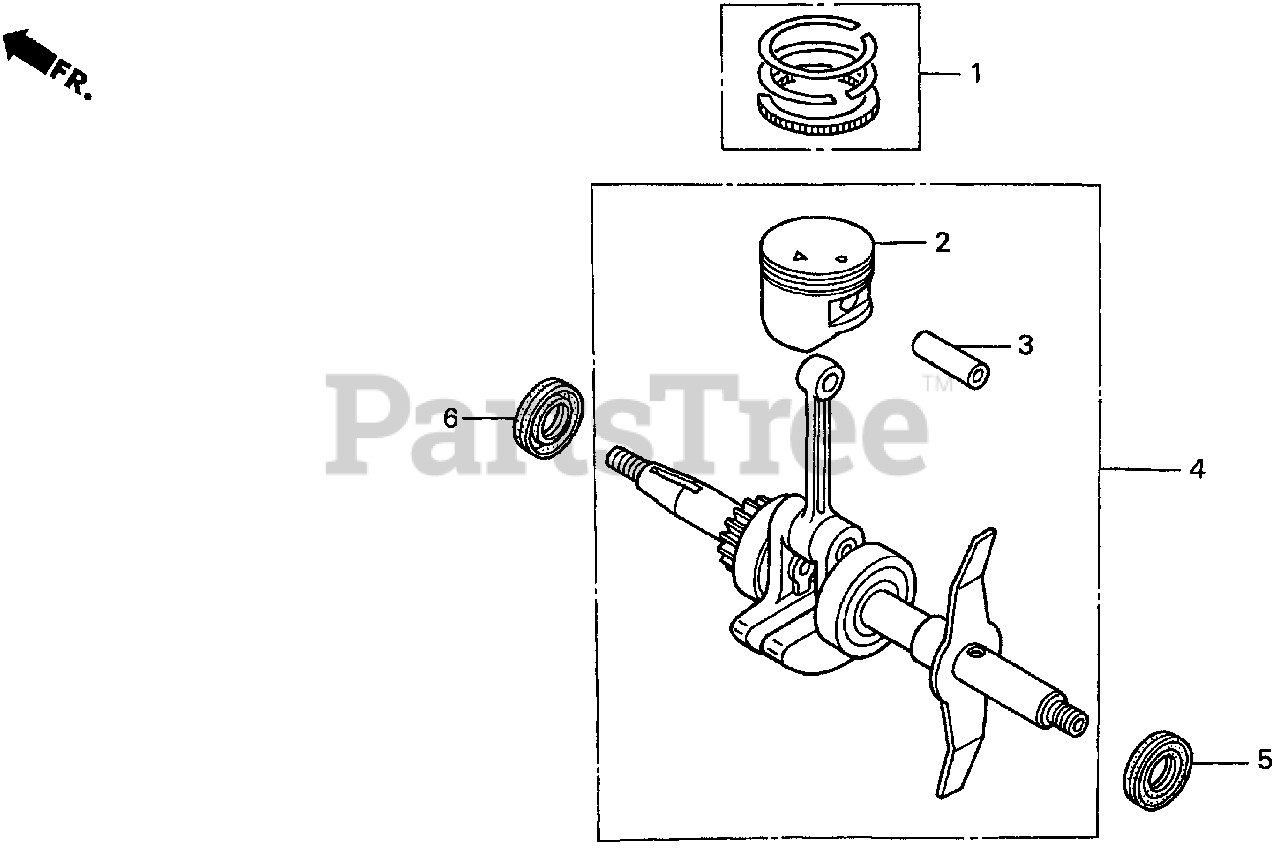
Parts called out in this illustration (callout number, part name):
1	RING SET, PISTON
2	PISTON
3	PIN, PISTON
4	CRANKSHAFT
5	OIL SEAL (12X25X6)
6	OIL SEAL (15X25X6)
